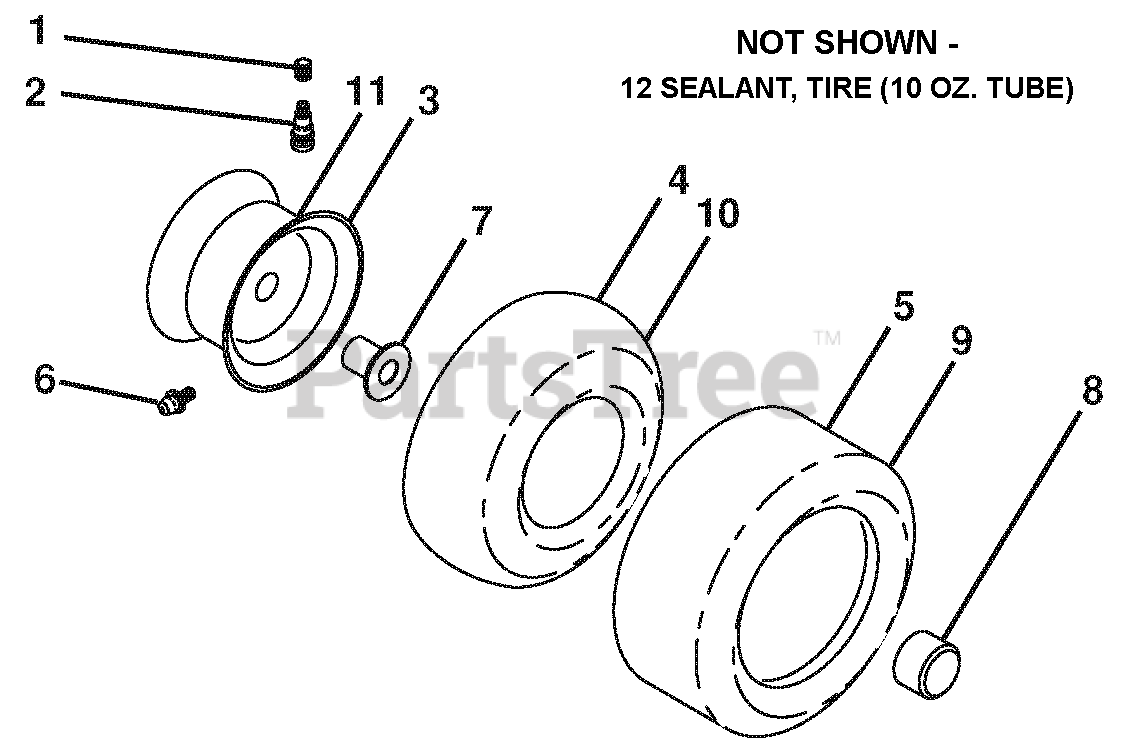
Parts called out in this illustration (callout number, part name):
1	CAP.VALVE.TIRE
2	STEM.VALVE
3	RIM.ASM.6"FRONT .643
4	TUBE.INNER.FRONT.#35060
5	TIRE.F.TS.15 X 6.0 - 6.SERVICE
6	FITTING.GREASE
7	BEARING.FLANGE
8	CAP.HUB.AXLE.W.GRY.1.50 X 1.00
9	TIRE.R.TS.20 X 8-8.C.SERVICE
10	TUBE.REAR.9.5 X 8.SERVICE
11	RIM ASM.8"REAR.W.GRY.SRVCE.643
